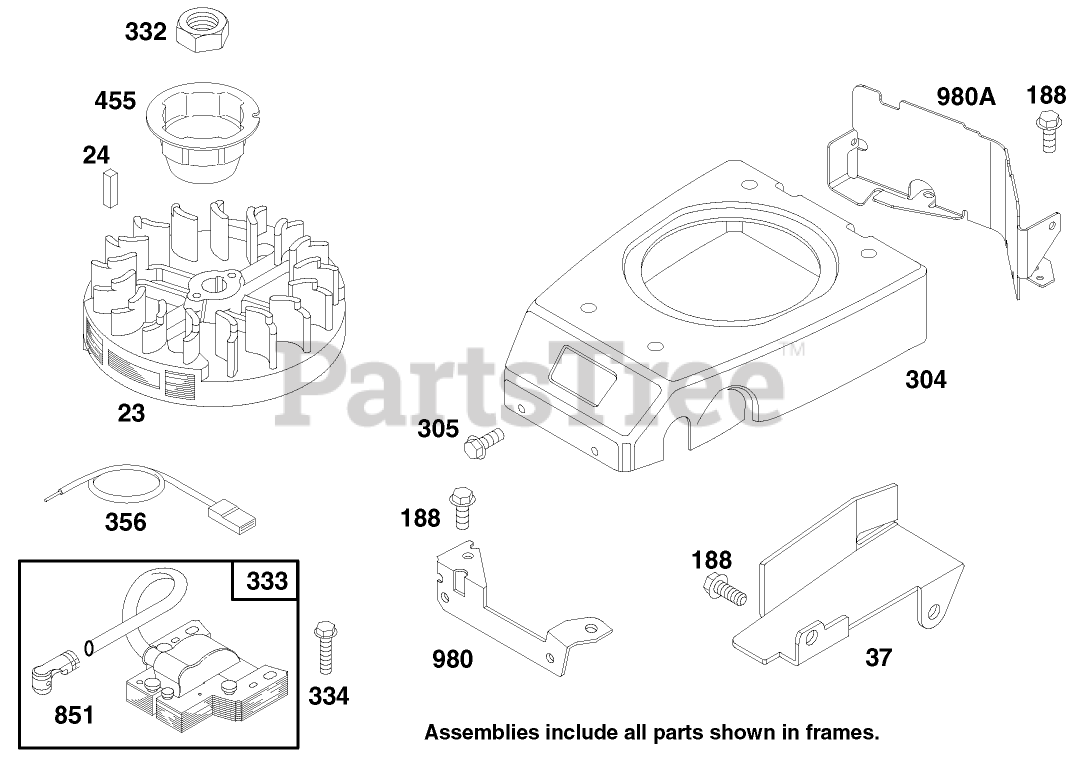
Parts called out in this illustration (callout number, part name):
24	KEY - FLYWHEEL
188	SCREW - HEX HEAD
304	BLOWER HSG ASM
305	SCREW - HEX HEAD
332	NUT - HEXAGON
356	WIRE - GROUND
980A	BLOWER HSG BRACKET
